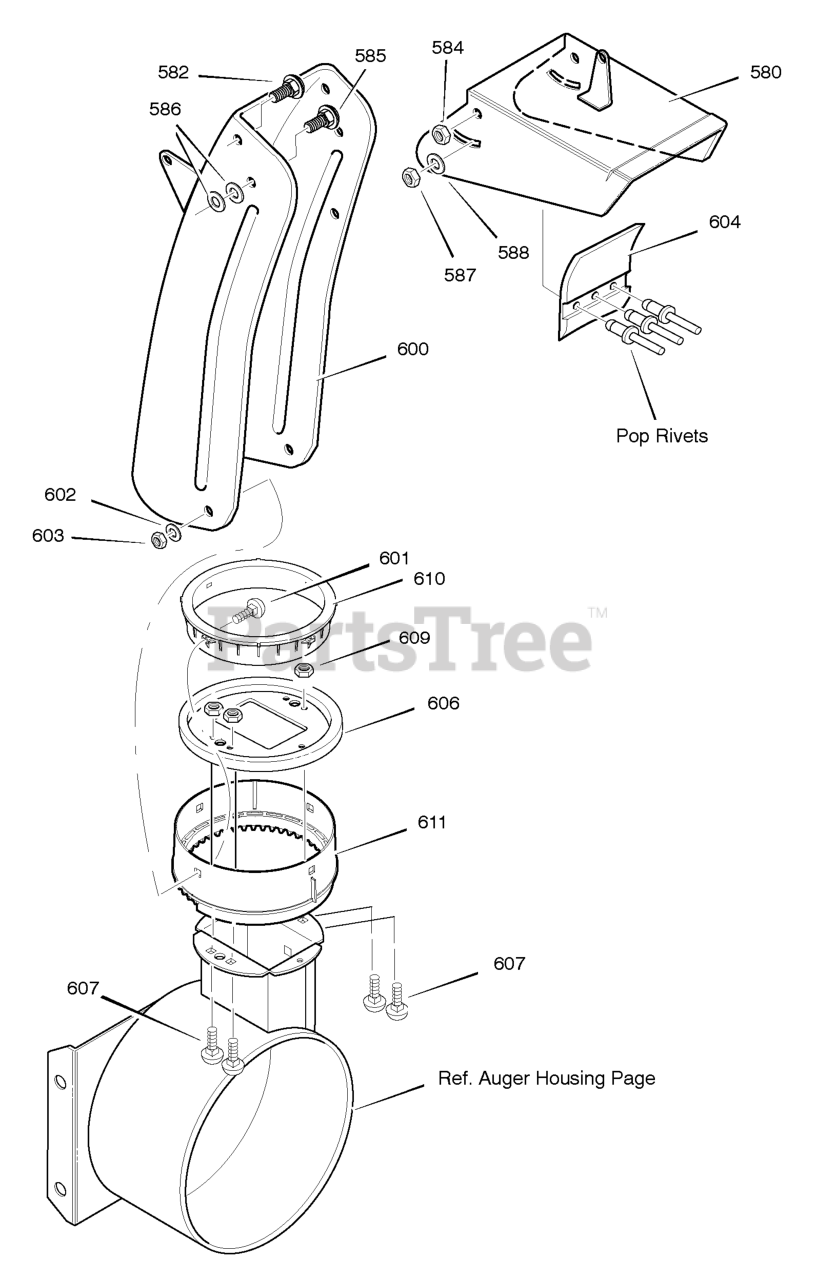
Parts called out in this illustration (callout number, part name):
580	CHUTE, UPPER W/REMOTE
582	SCREW, 5/16-18 x 0.75
584	NUT, 5/16-18
585	SCREW, 5/16-18 x 0.75
586	PLASTIC WASHER
587	NUT, 5/16-18
588	PLASTIC WASHER
600	CHUTE, LOWER W/REMOTE
601	BOLT, 5/16-18 x 1.00
602	WASHER, FLAT
603	NUT, 5/16-18
606	CHUTE COLLAR
607	BOLT, 1/4-20 x 0.75
609	NUT, 1/4-20
610	RETAINER, RING INNER
611	RETAINER, RING OUTER
